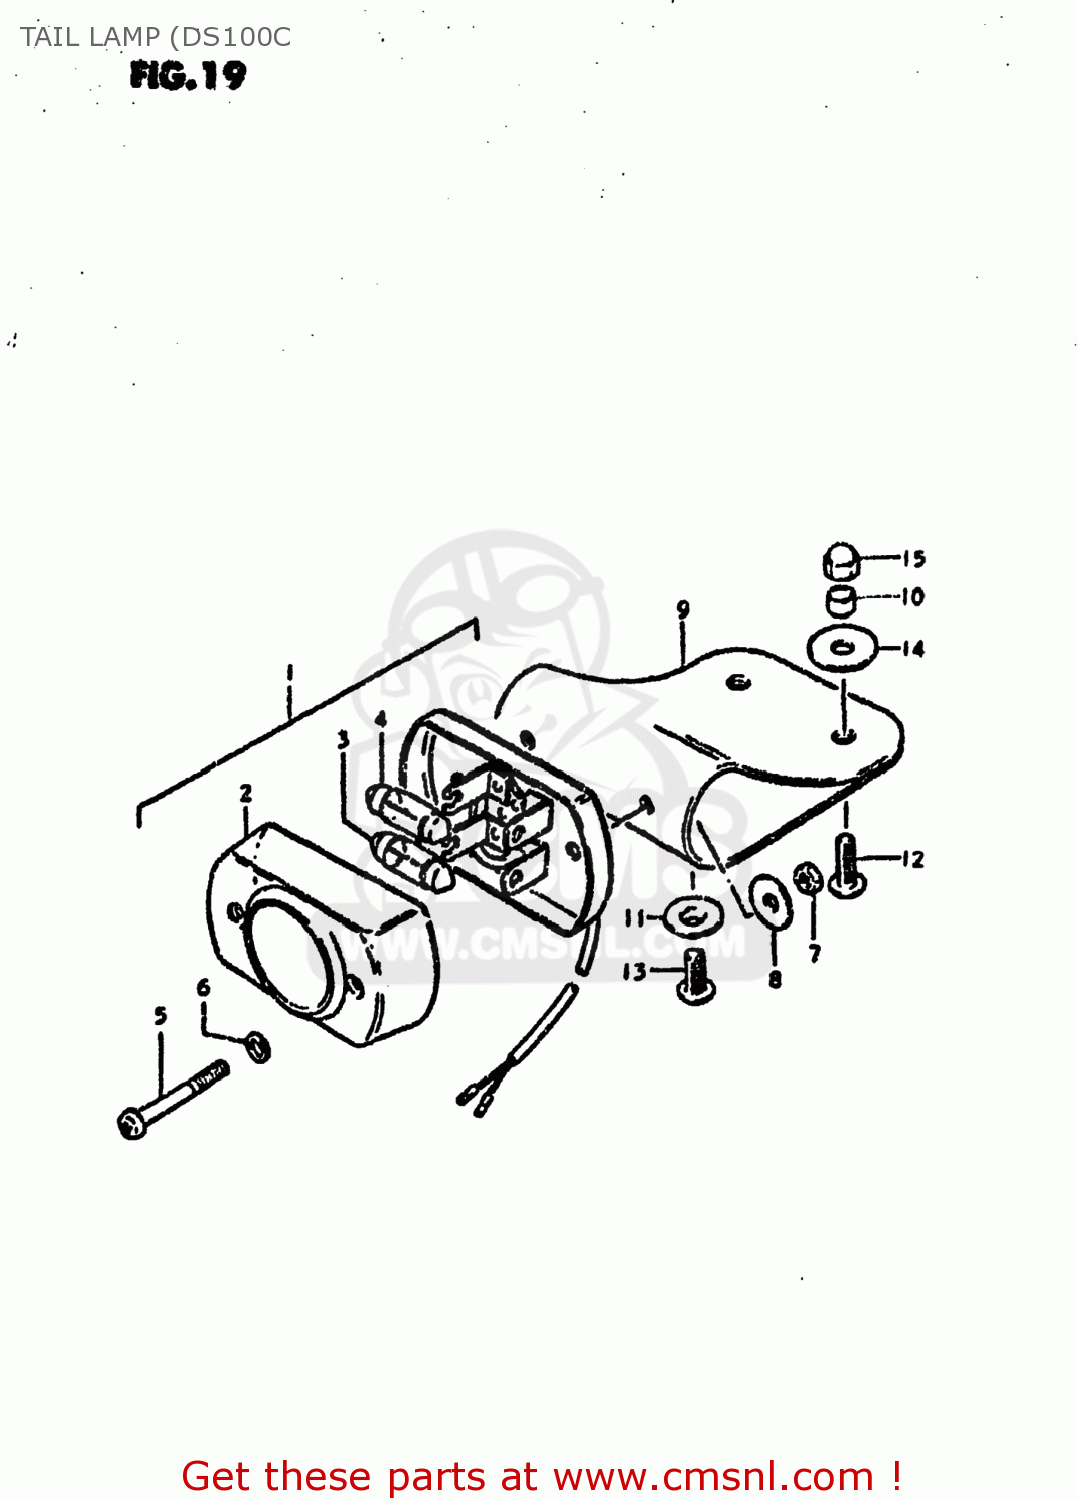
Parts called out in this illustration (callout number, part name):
1	LAMP ASSEMBLY,REAR COMBINATION
2	LENS,REAR COMBINATION LAMP
3	BULB
4	BULB 6V 8W
5	SCREW,REAR COMBINATION LAMP LENS
6	WASHER,REAR COMBINATION LAMP
7	NUT
8	WASHER(5.2X16X1)
9	CUSHION,REAR COMBINATION LAMP
10	SPACER(6.2X8.3X5.7)
11	WASHER
12	SCREW 6X12
13	SCREW 6X12
14	WASHER (6.5X20X1.2)
15	NUT
